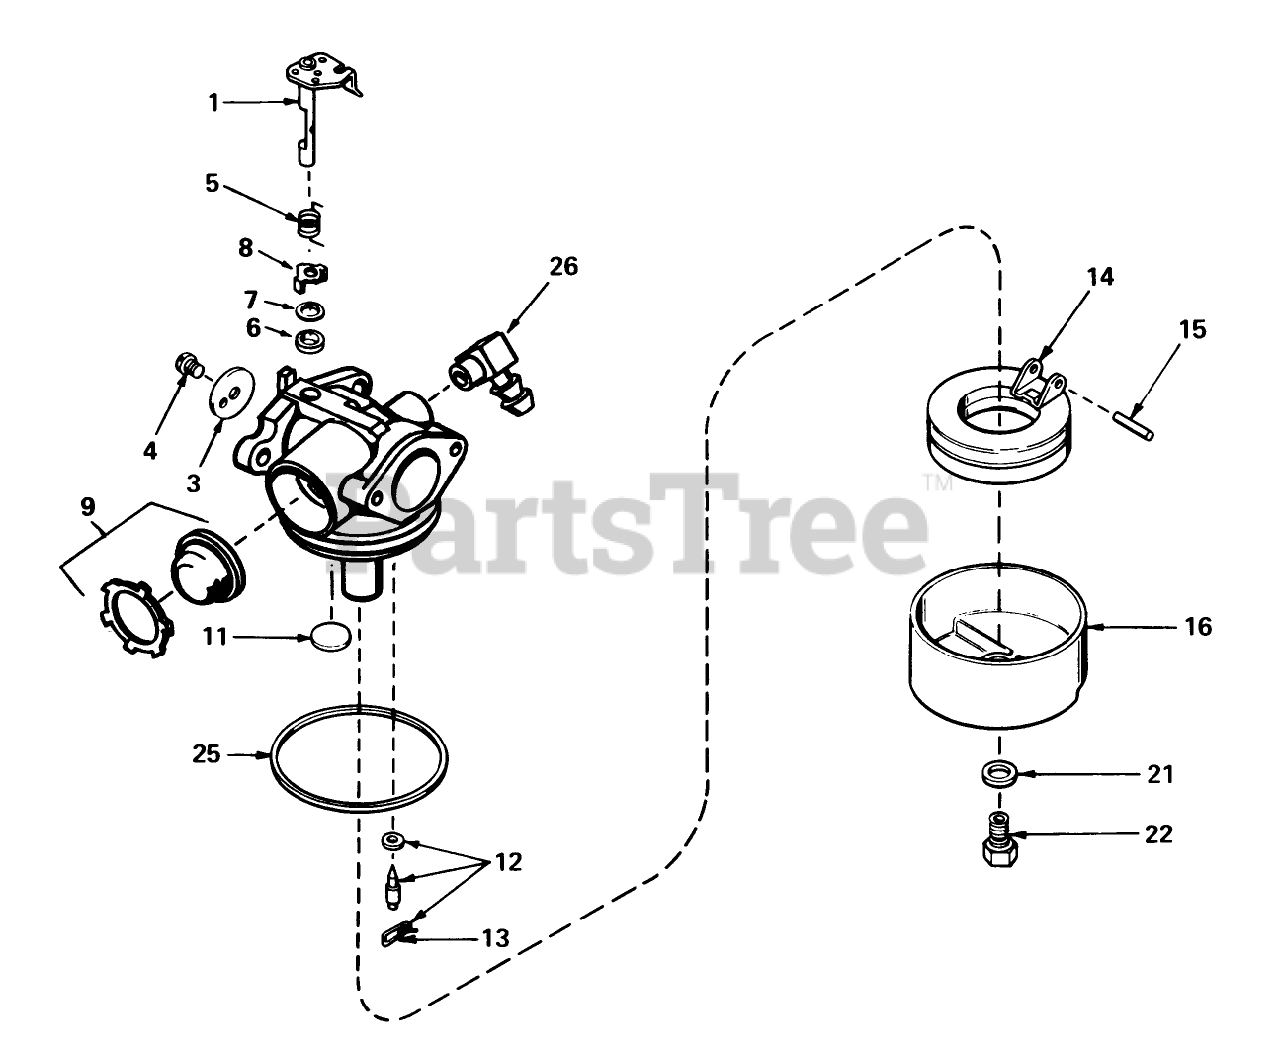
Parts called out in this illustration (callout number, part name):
1	Throttle Shaft and Lever ASM
3	Throttle-Shutter
4	Screw-Shutter
5	Spring, Return
6	Seal-Dust
7	Washer-Seal, Dust
8	Retainer, Seal
9	Primer Assy.
11	Plug-Welch, Atmospheric Vent
12	Inlet Needle, Seat Clip Assy. (Incl. No. 13)
13	Clip-Spring
14	Float
15	Shaft-Float
16	Bowl Float
21	Gasket-Bowl
22	Nut-Float Bowl
25	O Ring-Bowl, Float
26	Fitting-Fuel
